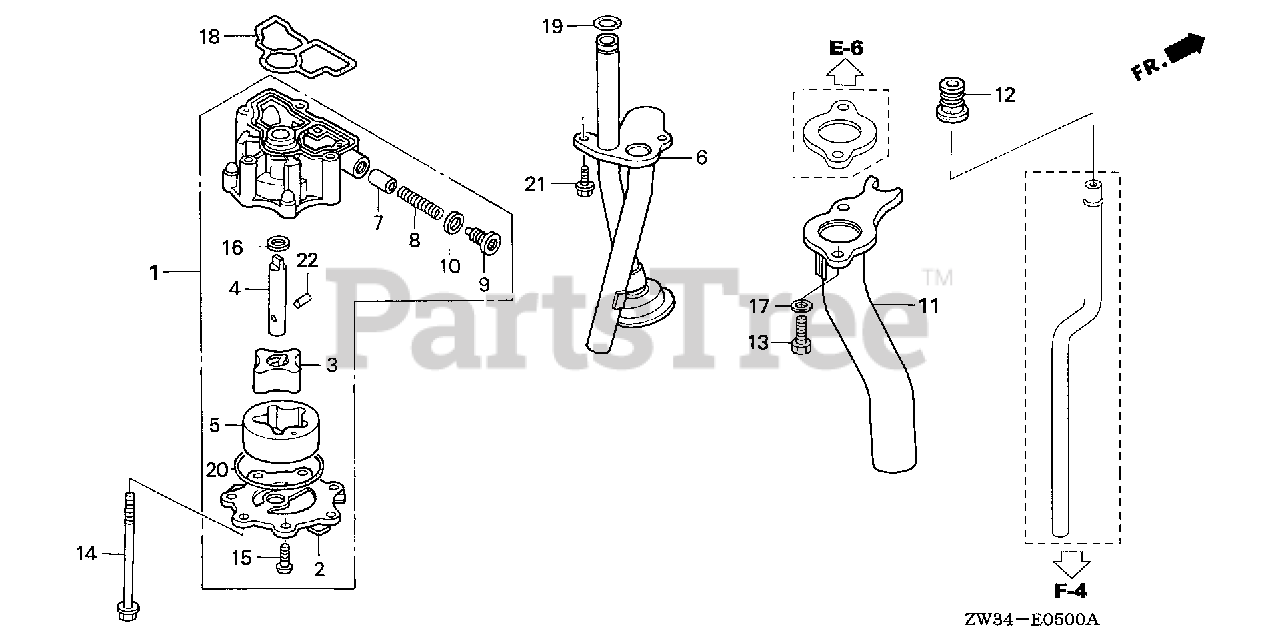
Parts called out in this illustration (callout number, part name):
1	PUMP ASSY., OIL
2	COVER, OIL PUMP
3	ROTOR (INNER)
4	SHAFT, OIL PUMP
5	ROTOR A (OUTER)
6	STRAINER, OIL
7	VALVE, RELIEF
8	SPRING, RELIEF VALVE
9	BOLT, SEALING (14MM)
10	WASHER, SEALING (14MM)
12	GROMMET, WATER TUBE
13	BOLT, HEX. (8X25)
14	BOLT, FLANGE (6X55)
15	SCREW, PAN (6X16)
16	WASHER, THRUST (13MM)
17	WASHER, PLAIN (8MM)
18	O-RING, PUMP COVER
19	O-RING (13.8X2.5)
20	O-RING (54X2.4) (ARAI)
21	BOLT, FLANGE (6X16)
22	ROLLER (5X17.8)
